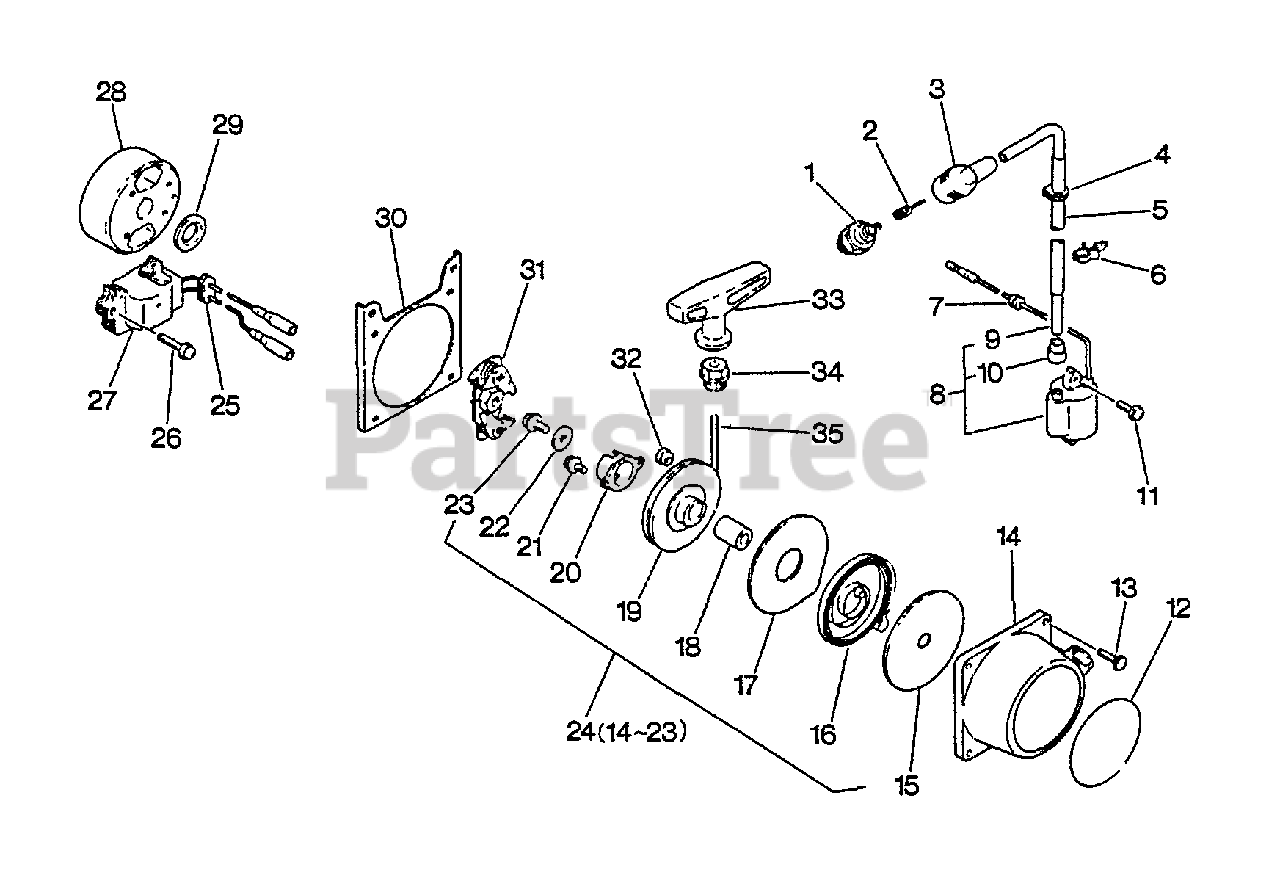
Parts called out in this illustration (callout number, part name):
1	SPARK PLUG - BPM7A
2	TERMINAL, SPARK PLUG
3	CAP, SPARK PLUG
5	TUBE, IGNITION COIL 6×8×340
8	COIL, IGNITION
11	SCREW 4×14
12	LABEL, ECHO
13	SCREW 4×16
14	CASE, STARTER
15	PLATE, SIDE
16	SPRING, RECOIL
17	PLATE, SIDE
19	REEL, ROPE
20	PAWL CATCHER
21	SCREW 4×8
22	WASHER 5.2×16×1.0
23	SCREW 5×10
24	STARTER ASSY
26	SCREW 4×20
27	COIL, IGNITION
28	FLYWHEEL
31	PAWL ASSY, STARTER
32	CLIP, STARTER ROPE
33	GRIP, STARTER
34	GUIDE, ROPE
35	ROPE, STARTER 3.5×850
